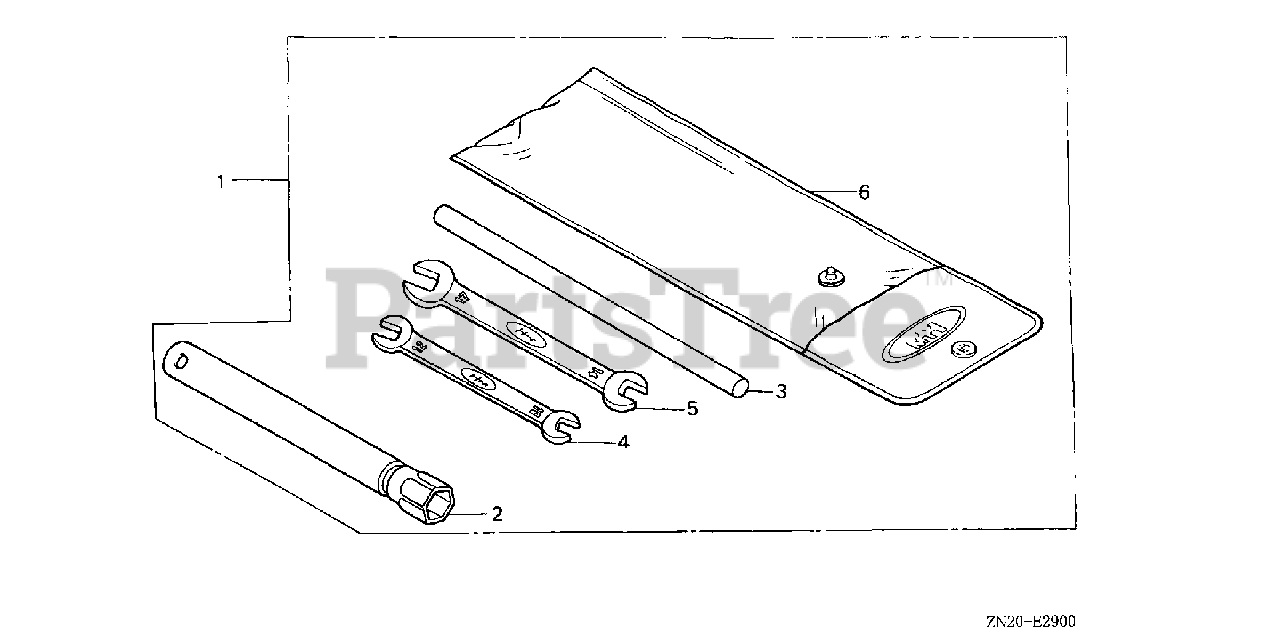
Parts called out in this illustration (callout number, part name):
1	TOOL KIT
2	WRENCH, SPARK PLUG
3	HANDLE, BOX WRENCH (NOT AVAILABLE)
4	WRENCH (10X12) (OPEN END)
5	WRENCH (14X17) (OPEN END)
6	BAG, TOOL (230MM)
